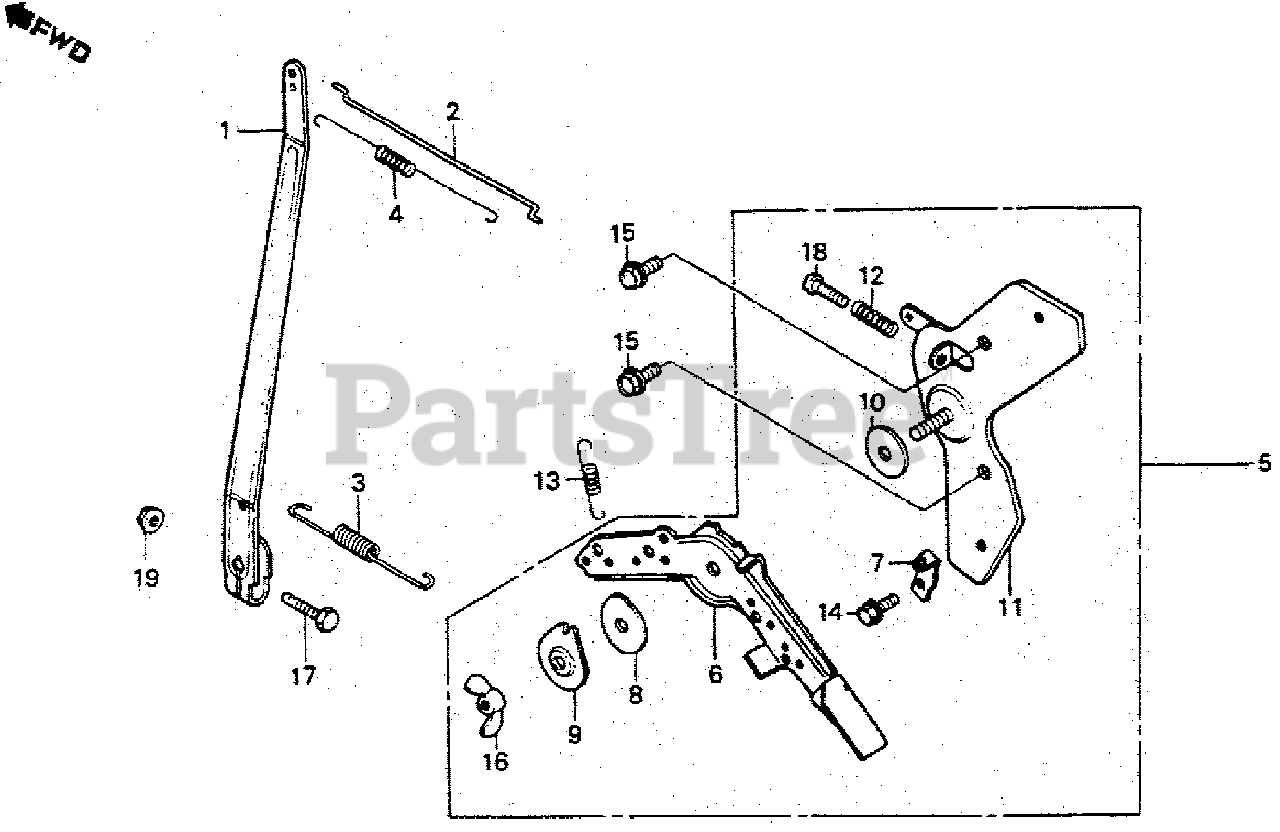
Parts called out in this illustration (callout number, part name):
1	ARM, GOVERNOR
2	ROD, GOVERNOR
3	SPRING, GOVERNOR
4	SPRING, THROTTLE RETURN
5	CONTROL ASSY. (NOT AVAILABLE)
6	LEVER, CONTROL (NOT AVAILABLE)
8	SPRING, LEVER
9	WASHER, CONTROL LEVER
10	SPACER, CONTROL LEVER
11	BASE, CONTROL LEVER
12	SPRING, CONTROL ADJUSTING
13	SPRING, CABLE RETURN
14	BOLT, FLANGE (5X10)
15	BOLT, FLANGE (6X12) (CT200)
16	WINGNUT (6MM)
17	BOLT, HEX. (6X20)
18	SCREW, PAN (5X22)
19	NUT, FLANGE (6MM)
